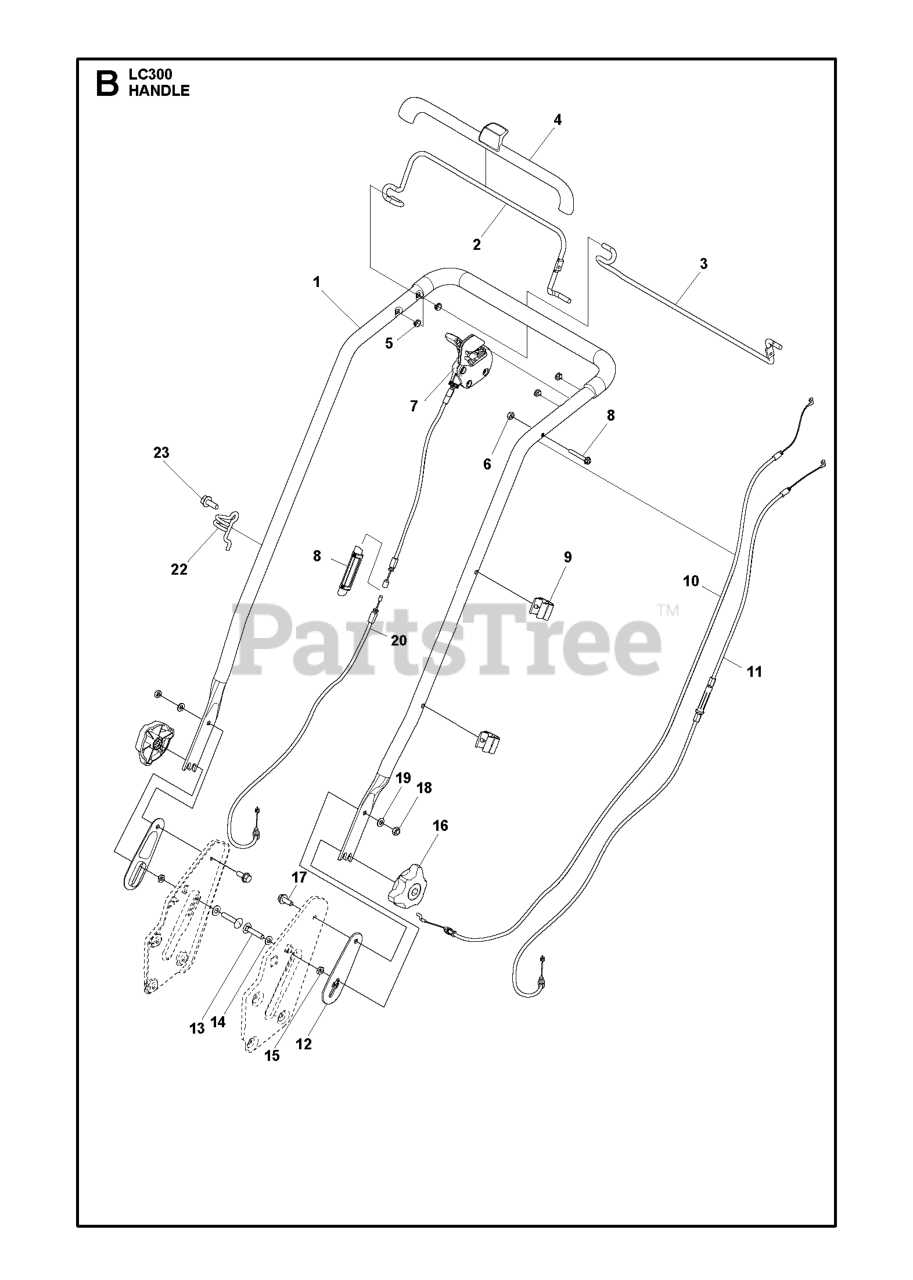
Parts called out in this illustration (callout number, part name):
6	NUT FLANGE - M6
15	NUT ML6M M8
18	LOCKNUT M8
23	SCREW
